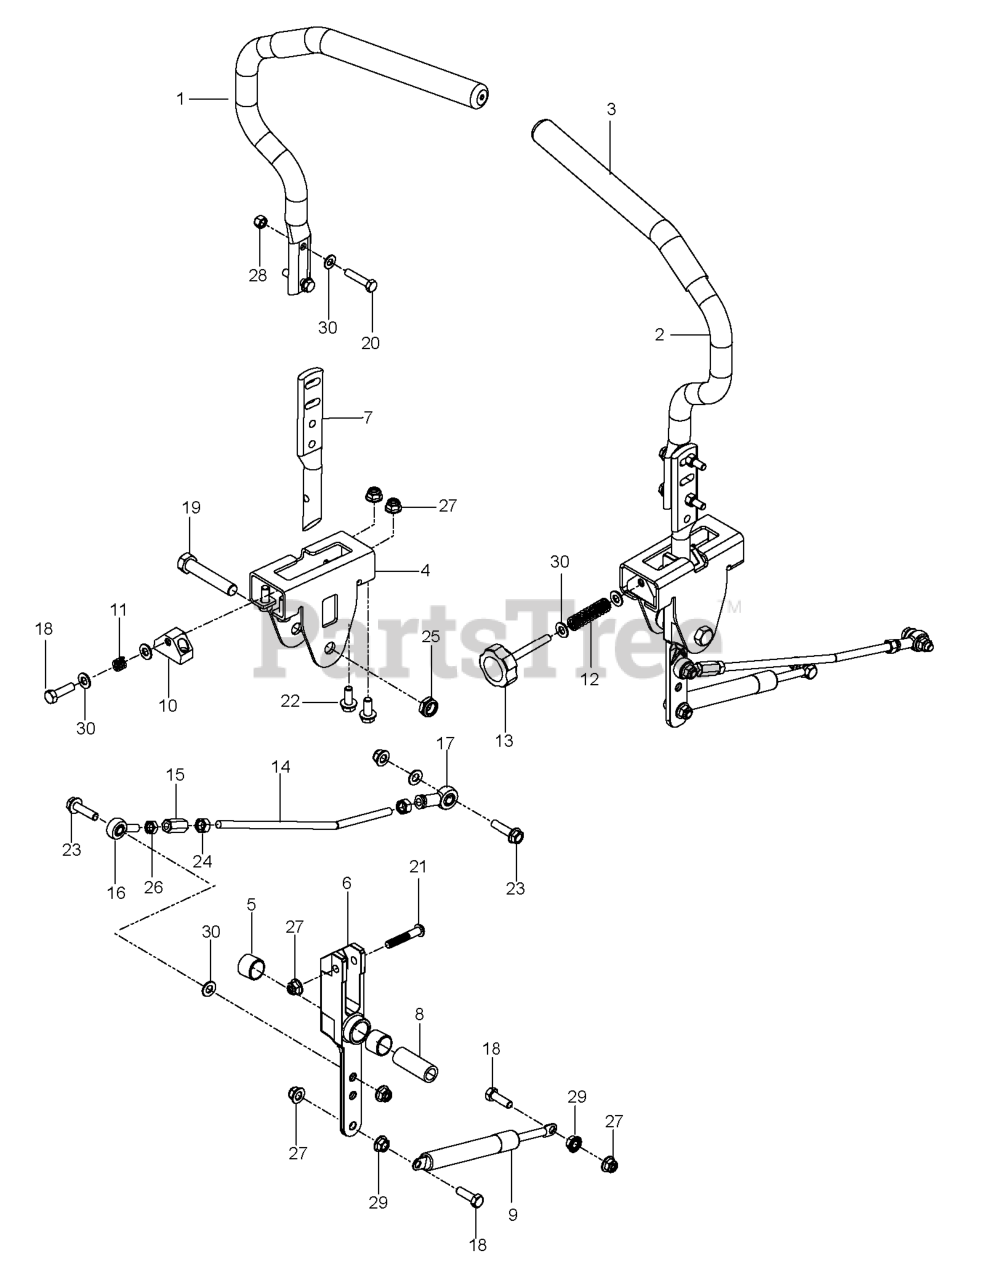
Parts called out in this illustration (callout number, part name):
1	LEVER.DRIVE.W/GRIP.RIGHT
2	LEVER.DRIVE.W/GRIP.LEFT
3	GRIP - DRIVE LEVER 12"
4	BRACKET, CONTROL
5	BEARING
6	CONTROL.WELDMENT.RZ
7	LEVER.HANDLE MOUNT
8	SPACER.PIVOT.CONTROL
10	BLOCK TRACKING CONTROL ZTR
12	SPRING COMPRESSION 2.0
13	KNOB
14	ROD, CONTROL
15	ROD END COUPLER
16	ROD.END.MALE.LH.THREAD
17	RH ROD END
18	BOLT.5/16-18X1-1/4 FULL.THREAD
19	HCS 1/2-13 X 2-3/4 GD 5 ZD
20	CAPSCREW 5/16 X 1/1/2 HEX HEAD
21	SCREW 5/16-18 X 1 3/4 BTN-HD
22	HHFS 5/16-18 X 3/4
23	HHFS 5/16-18 X 1.25 TPBLT GD 5
25	NUT 1/2-13 HEX JM NYL
26	NUT 5/16F LEFTHAND
27	5/16-18 NYLOC FLANGE NUT
28	NUT 5/16 NYLOC
29	NUT 5/16C WHIZ
30	WASHER
